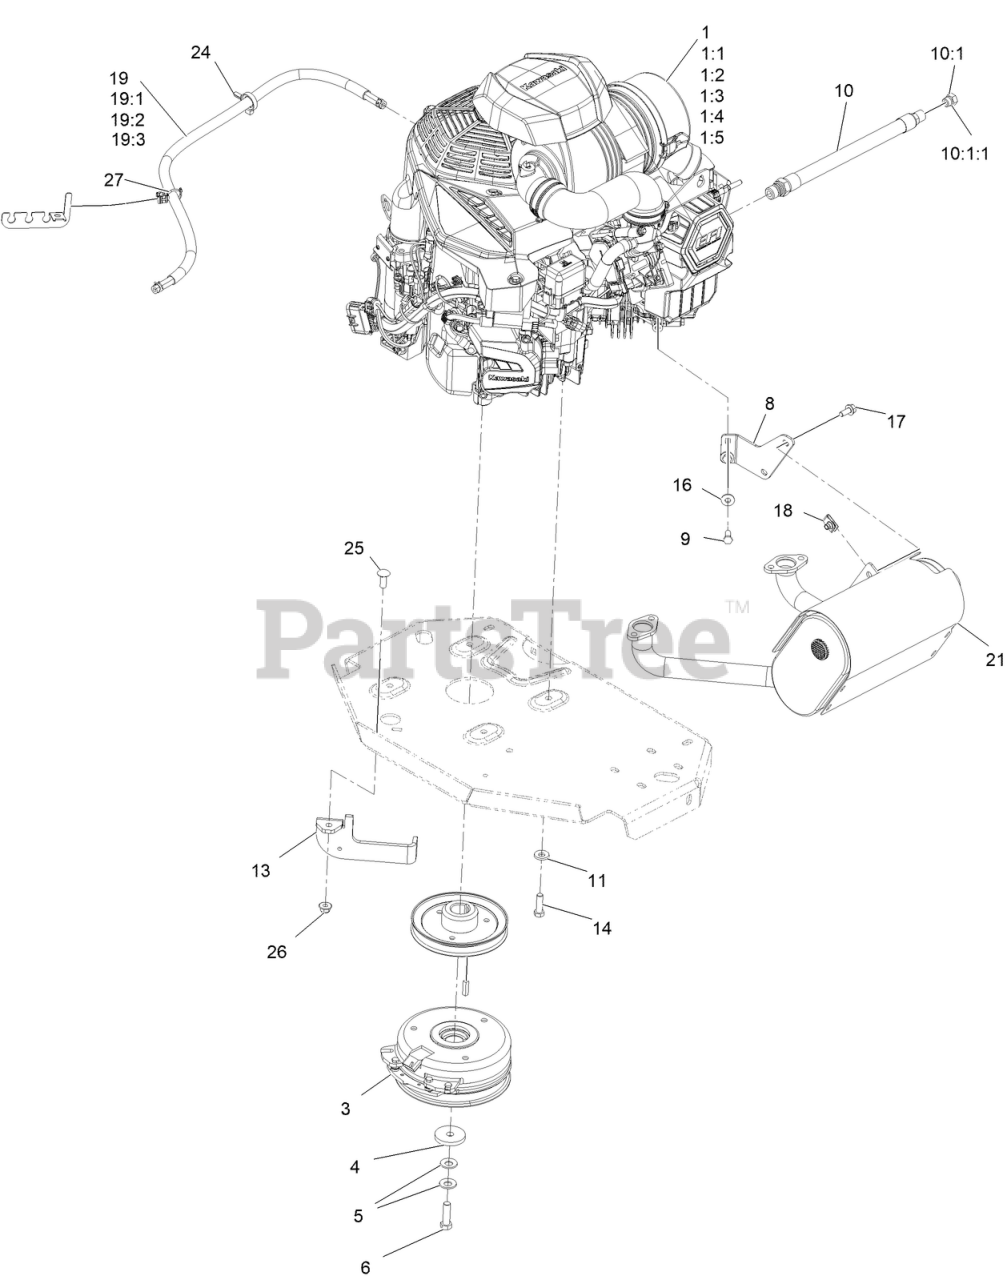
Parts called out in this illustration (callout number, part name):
1:1	FILTER-OIL KAW
1:2	ELEMENT-FILTER, AIR (OUTE
1:3	ELEMENT-FILTER, AIR (INNE
1:4	FILTER-FUEL
1:5	SPARK PLUG
3	CLUTCH KIT
4	WASHER-CLUTCH
5	WASHER-SPRING
6	SCREW-HH 7/16-20 X 1 1/2 W/LOCTITE
8	BRACKET-MUFFLER 820KAW
9	SCREW-HH
10	ENGINE OIL DRAIN HOSE ASM
10:1	PLUG-HH
10:1:1	O-RING
11	WASHER-BELLEVILLE
13	Bracket-Clutch Anchor
14	SCREW-HH
16	WASHER-SPRING
17	SCREW-HHF
19	FUEL LINE ASM
19:1	HOSE-FUEL
19:2	SLEEVE-THERMAL
19:3	CLAMP-HOSE
21	MUFFLER-KAWASAKI FX820V
24	CLAMP-HOSE
25	SCREW-CARR
26	NUT-HF, NI
27	Clip-Edge
